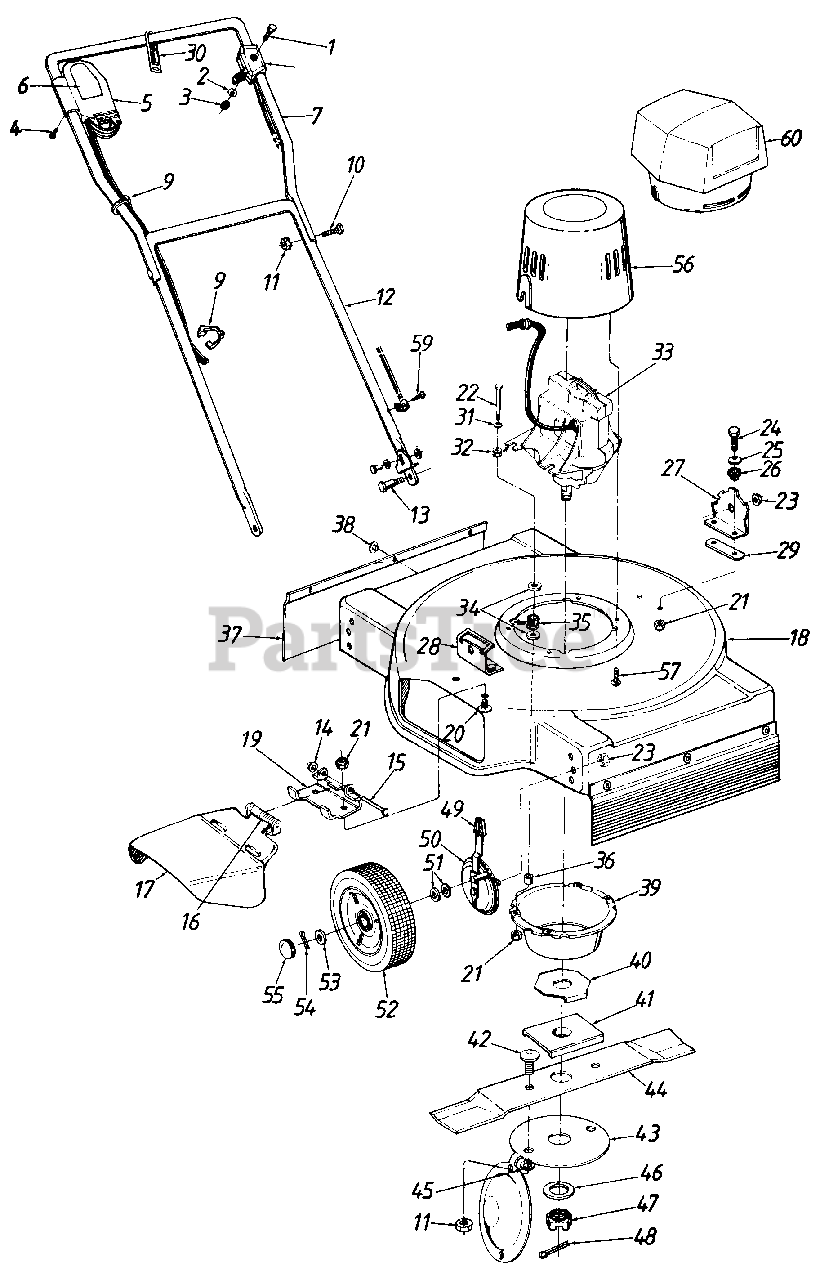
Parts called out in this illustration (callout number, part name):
1	Hex Bolt 1/4-20 x 1.5"
2	Washer
3	Acorn Nut 1/4-20 Thd.
4	Hi-Lo Screw #7 x 1"
5	Cord & Switch Box Comp.
6	Label-Switch Box
7	Upper Handle
9	Cable Tie
10	Hex Bolt 5/16-18 x 1-1/4 " Lg.
11	Hex Sems Nut 5/16-18 Thd.
12	Lower Handle
13	Shoulder Bolt
14	Cap Speed Nut 1/4" I.D.
15	Hinge Pin
16	Torsion Spring
17	Chute Deflector Ass'y.
18	19" Deck Ass'y.
19	Adapter Plate
20	Carriage Bolt 1/4-20 x 518" Lg.
21	Hex L-Nut 1/4-20 Thd.
22	Hex Bolt 1/4-20 x 2 1/2" Lg. (Grade 5)
23	Hex Sems Nut 3/8-16 Thd
24	Hex/Bolt 1/4-20 x 718"
25	Fl-Wash. 1/4" I.D.
26	Insulator
27	Handle Bracket-L.H.
28	Handle Bracket-R.H.
29	Insulator Strip
30	Cord Restraint
31	Fl-Wash. 1/4" I.D. x 3/4" O.D.
32	Insulator
33	Motor & Switch Ass'y. Comp.
34	Fl-Wash. 1/4" I.D. x 1" O.D.
35	Grommet Ass'y.
37	Rear Flap
38	Rivet
39	Motor Shield
40	Blade Adapter
41	Adapter Insulator
42	Carriage Bolt 5/16-18 x 3/4" Lg.
43	Blade Insulator
44	19" Blade
45	Bolt Retainer
46	Fl-Wash. 1/2" I.D. H.T.
47	Castle Nut 1/2" I.D.
48	Coter Pin
50	Height Adj. Ass'y.
51	Fl-Wash. 1/2" I.D.
52	7" Wheel Ass'y.
53	Fl-Wash. 1/2" I.D.
54	Coter Pin
55	Hub Cap
56	Motor Cover
57	Self-Tap Scr. #10-16 x 3/4" Lg.
60	Motor Cover
